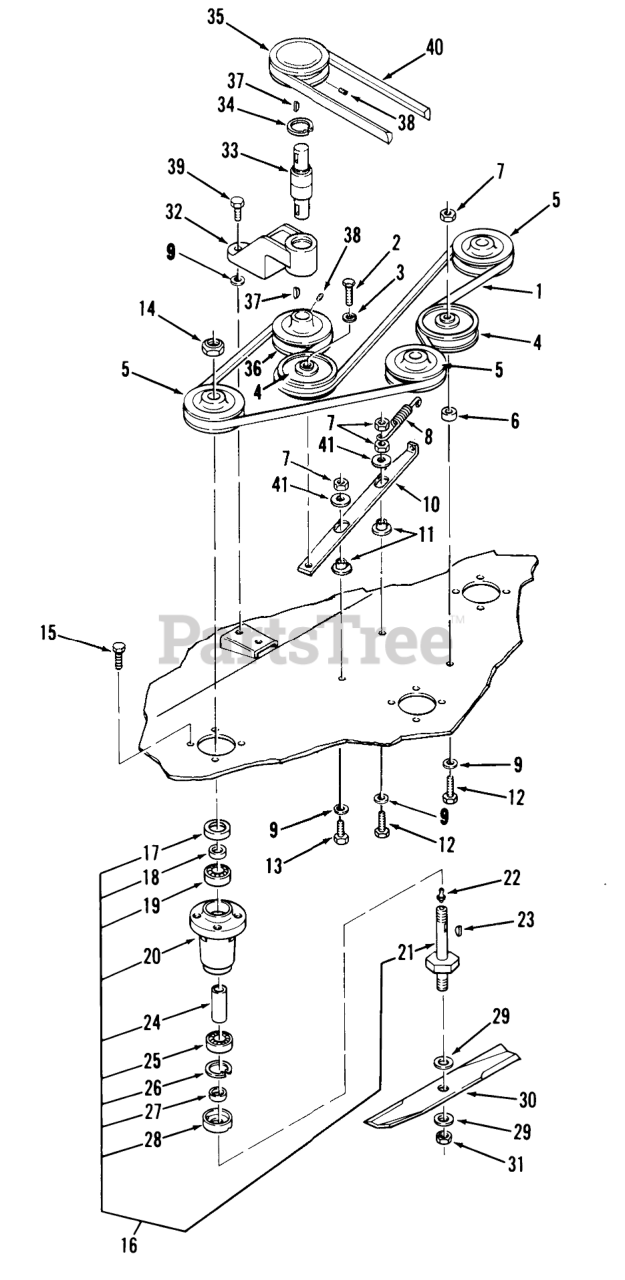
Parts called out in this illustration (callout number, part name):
1	BELT-V
2	BOLT HEX SPECIAL
3	LOCKWASHER
4	Idler Pulley
5	PULLEY-BLADE DRIVE
6	SPACER
7	Nut
8	SPRING-EXTENSION
9	WASHER
10	BAR-IDLER SUPPORT
11	SPACER-BUSHING
12	Bolt
13	Bolt
14	Nut
15	Bolt
16	Spindle Assembly
18	SPACER-SEAL
19	BEARING-BALL
20	HOUSING-SPINDLE
21	Spindle Shaft
22	Grease Fitting
23	Hi-Pro Key 3/16 x 5/8
24	SPACER
25	BEARING-BALL
26	Ring-Snap
27	SPACER-BLADE
28	CUP-SPINDLE
29	SpeciaI Washer
30	S/A BLADE KIT
31	Nut
32	HOUSING DRIVE BRG R
33	BEARING-INT SHAFT
34	Snap Ring
35	PULLEY
36	Pulley
37	KEY-WOODRUFF
38	Set Screw
39	Bolt
40	V-BELT
41	WASHER
